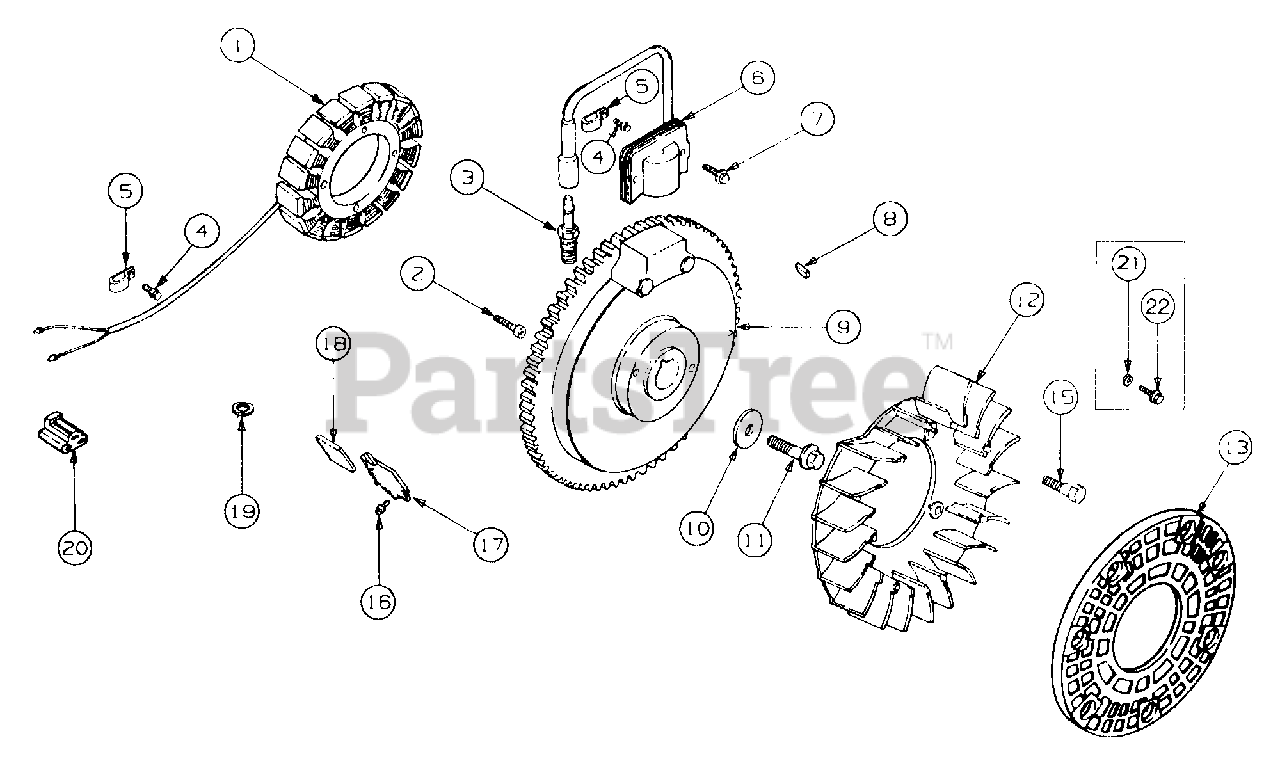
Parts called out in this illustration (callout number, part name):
1	Kit, Stator
2	Screw, Stator Mounting M5 x .8 x 25
3	Spark Plug
4	Screw, Stator Harness Clip, M5 x .8 x 10
5	Clip, Cable
6	Module, Ignition
7	Screw, Ign Module, M5 x .8 x 20
9	Flywheel Assy
10	Washer, Flywheel
11	Screw, Flywheel, M5 x 1.5 x 46
12	Fan
13	Screen, Grass
15	Bolt, Shoulder M6 x 1.0 x 16
16	Screw, Rectifier, M5 x 1 x 16
17	Rectifier-Regulator
18	Connector, 3 Contact
19	Washer, Lock, 1/4
20	Connector, 3 Contact
21	Spacer
22	Screw
